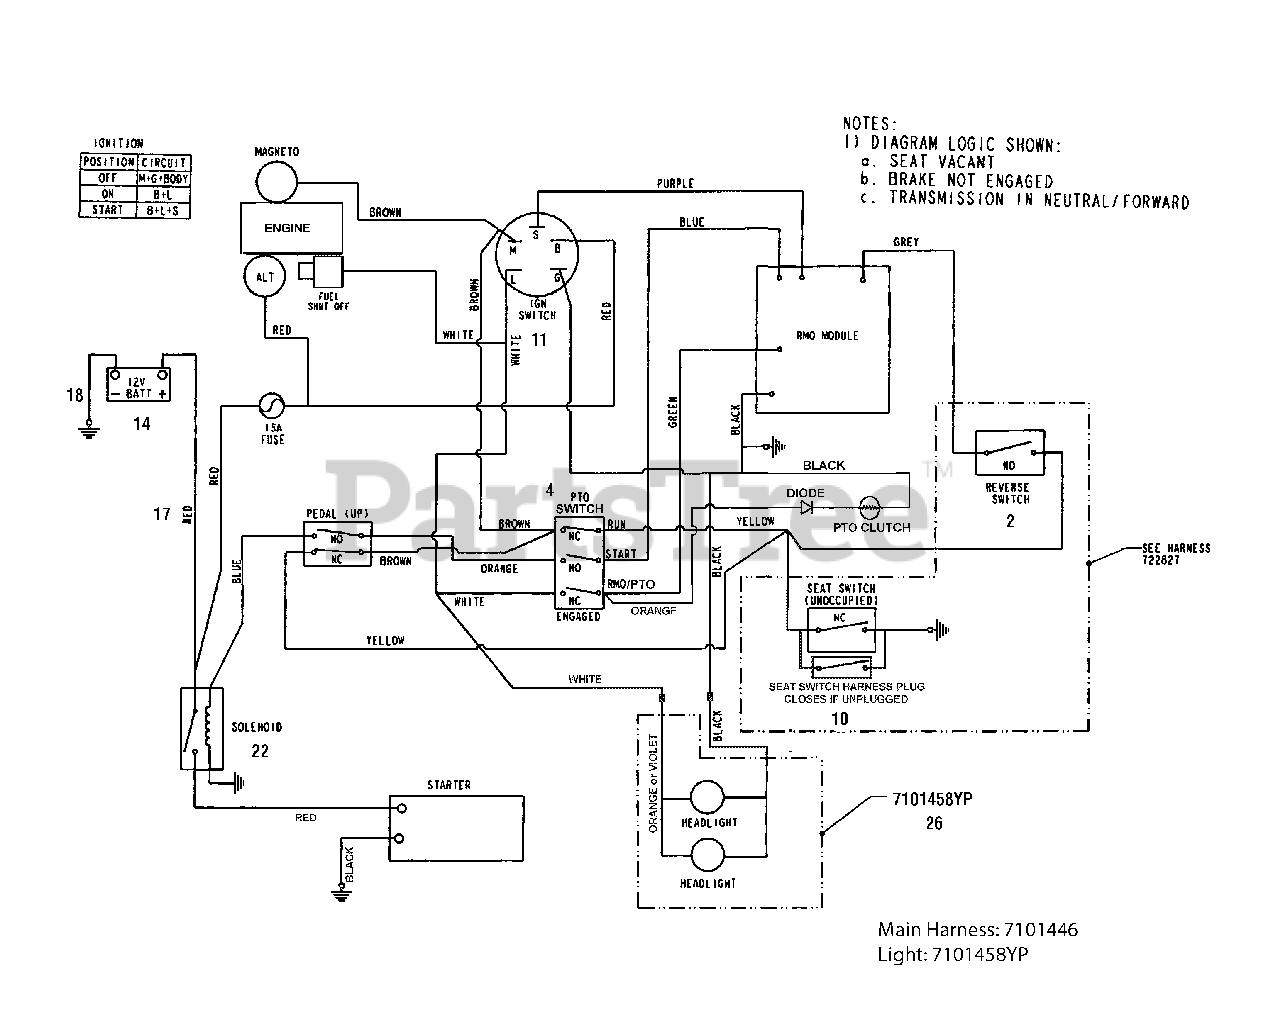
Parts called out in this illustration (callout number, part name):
1	KEY, Ignition, Indak, Set of 2
2	SWITCH, RMO Module Only
3	KEY, RMO Module, Plastic
4	SWITCH, Push Button, Electric PTO
5	KEY, W/Hang Tag, RMO
6	NUT, Hex, 1/4-20
7	LOCKWASHER, 1/4
8	WASHER, 5/8
9	CAPSCREW, Hex 1/4-20 x 3/4
10	SWITCH, Seat
11	SWITCH, Ignition
12	NUT, 5/8-32, ES
14	BATTERY, 12 VOLT, 230 CCA
15	WIRING HARNESS, Hydro Tractor, Electricl PTO
17	CABLE, Battery, 8 Gauge, Red
18	CABLE, Battery, 8 Gauge, Black
19	BOOT, Battery, Positive
20	SWITCH, LIMIT, NO / NC, Snap-in
21	SWITCH, LIMIT, NO, Snap-in
22	SOLENOID, 3 Pole
23	NUT, Hex Nylock 1/4-20
24	SCREW, 1/4-14 x 3/8
25	WIRING HARNESS, Seat Switch
26	HARNESS, Headlight
